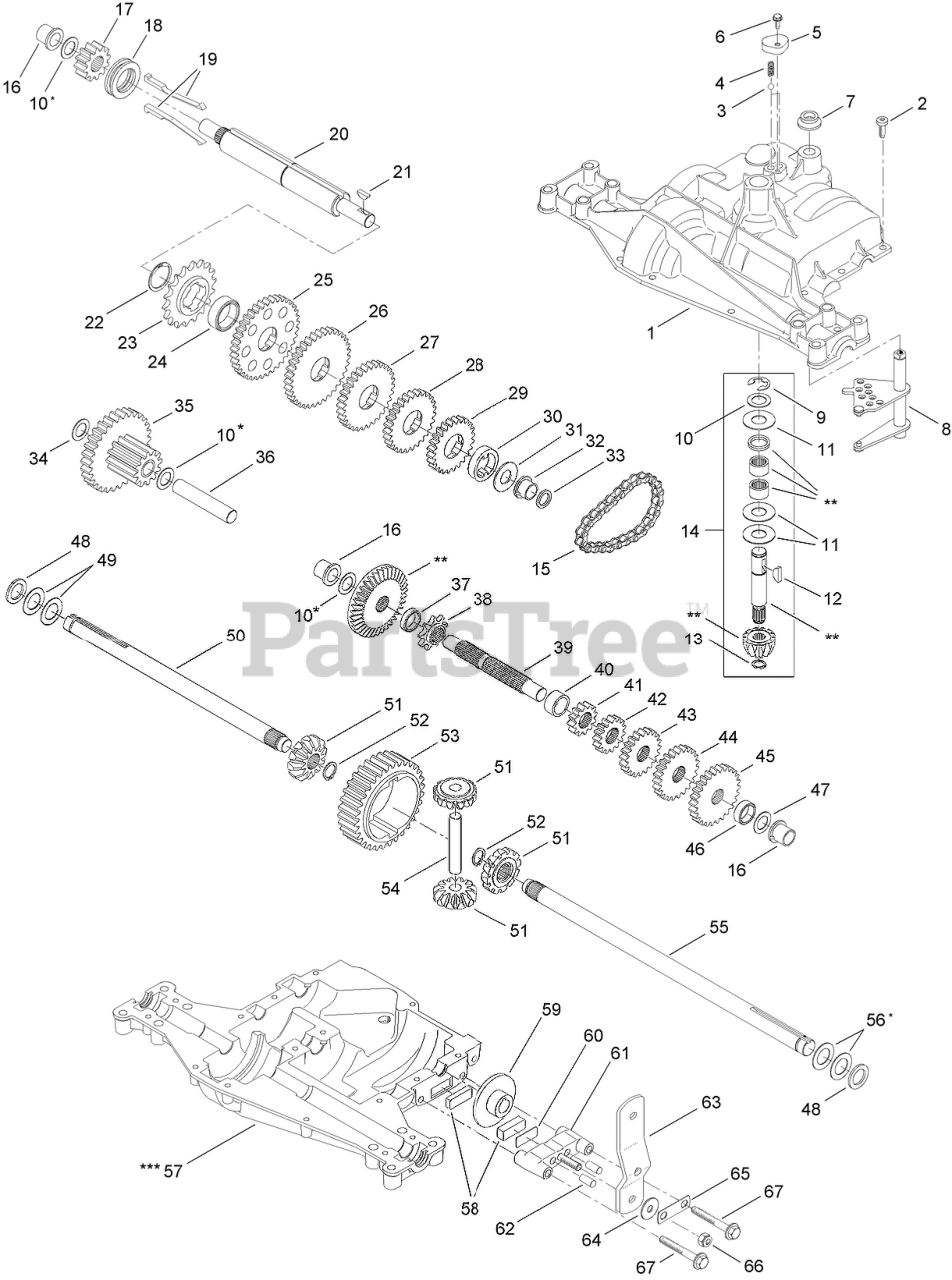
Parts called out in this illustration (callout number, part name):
1	HOUSING-UPPER
2	SCREW-TAPPING
3	BALL-DETENT
4	SPRING-DETENT
5	COVER-DETENT
6	SCREW-TAPPING
7	V-RING
8	SHIFTER KIT
9	RING-RETAINING
10	SHIM ASM (.625 SHAFT)
11	WASHER-PLAIN
12	KEY-WOODRUFF
13	RING-RETAINING
14	INPUT SHAFT KIT
15	CHAIN-PITCH, 24
16	BEARING-FLANGE
17	GEAR-SPUR, 12T
18	COLLAR-CLUTCH
19	CLUTCH KEYS ASM
20	SHAFT-INTERMEDIATE
21	KEY-WOODRUFF
22	RING-RETAINING
23	SPROCKET-18T
24	SPACER
25	GEAR-SPUR,37T
26	GEAR-SPUR, 35T
27	GEAR-SPUR,30T
28	GEAR-SPUR,25T
29	GEAR-SPUR,22T
30	SPACER
31	WASHER-PLAIN
32	BEARING-FLANGE
33	SEAL-OIL
34	WASHER-PLAIN
35	COMBINATION GEAR ASM (12T 30T)
36	SHAFT-IDLER
37	SPACER
38	SPROCKET-9T
39	SHAFT-DRIVE
40	SPACER
41	GEAR-SPUR,12T
42	GEAR-SPUR, 15T
43	GEAR-SPUR,20T
44	GEAR-SPUR,25T
45	GEAR-SPUR,28T
46	SPACER
47	WASHER-PLAIN
48	WASHER-NEOPRENE
49	WASHER-PLAIN
50	AXLE-LH
51	MITER GEAR KIT
52	RING-RETAINING
53	GEAR-SPUR, 32T
54	SHAFT-CROSS
55	AXLE-RH
56	SHIM ASM (.750 SHAFT)
57	HOUSING-LOWER
58	PUCK-BRAKE
59	DISC-BRAKE
60	SPACER-PUCK, BRAKE
61	JAW-BRAKE
62	PIN-DOWEL
63	LEVER-ACTUATING
64	WASHER-PLAIN
65	BRACKET-ROTATION, ANTI
66	NUT-LOCK
67	SCREW-TAPPING
